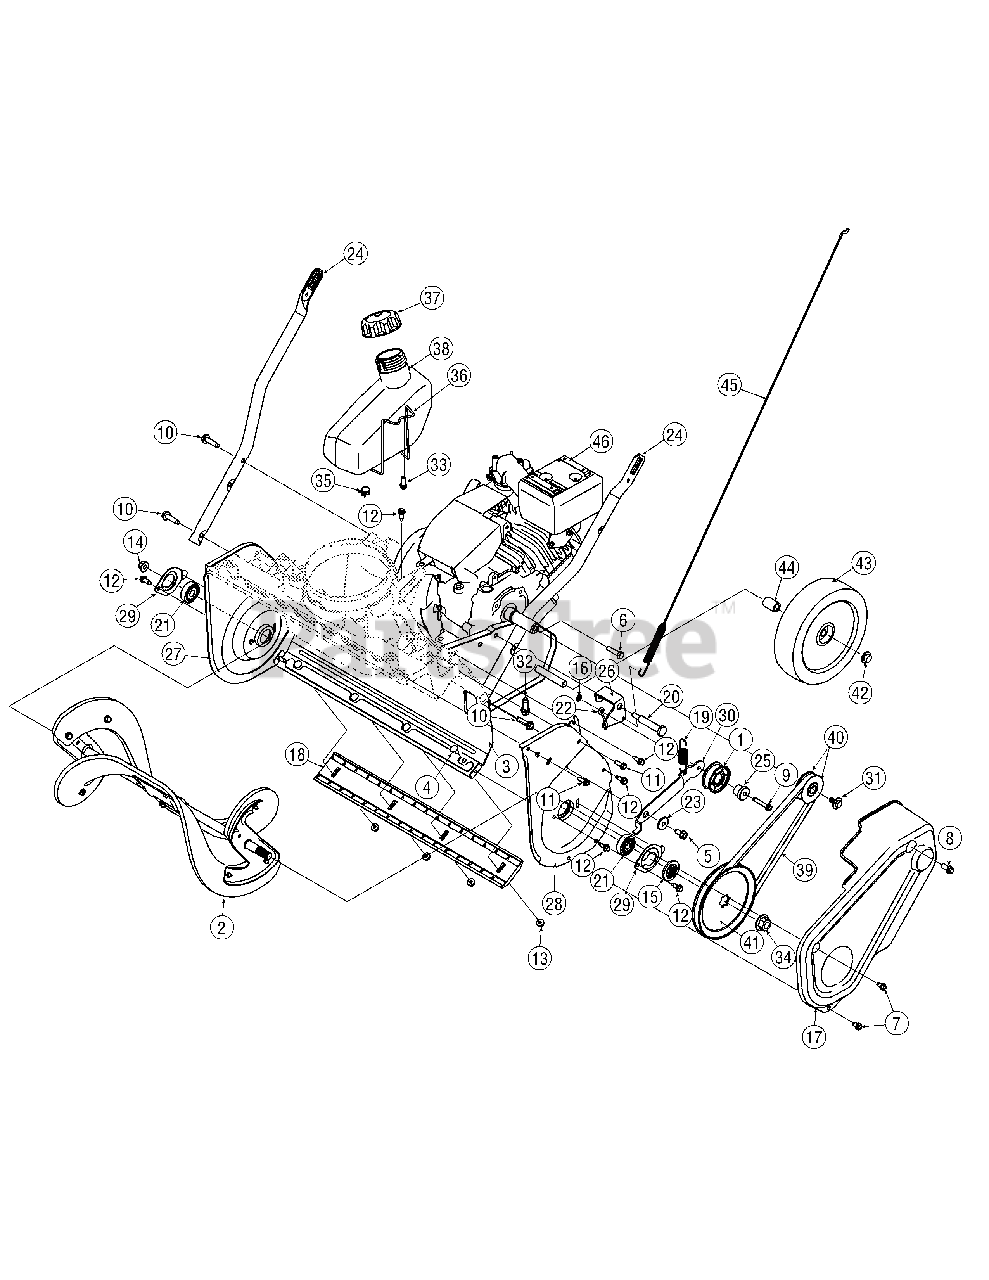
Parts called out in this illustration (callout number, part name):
1	Idler Pulley Assembly
2	Auger Assembly Complete
2	Hex Washer Screw 1/4-20 x.750
3	Frame Assembly
4	Carriage Screw, 1/4-20 x .62
5	Hex Washer Screw, 5/16-18 x .750
6	Hex Screw, 5/16-24 x 1.25
7	Hex Washer Screw, 1/4-20 x .500
8	Hex Lock Screw, 5/16-24 x .750
9	Hex Washer Screw, 1/4-20 x 1.500
10	Hex Washer Screw, 5/16-18 x 1.250
11	Hex Washer Screw, 1/4-15 x .750
12	Hex Washer Screw, 1/4-20 x .625
13	Flange Lock Nut, 1/4-20
14	Flange Lock Nut, 3/8-16
15	Pulley Hub
16	Push Nut, .25 x .50
17	Belt Cover
18	Shave Plate
19	Extension Spring, .70 x 3.035
20	Shoulder Bolt, 5/16-24 x .496 x 2.18
21	Ball Bearing, .5000 x 1.375 x .4375
22	Drive Cable Wire Support
23	Shoulder Spacer
24	Lower Handle
25	Shoulder Spacer
27	RH Side Plate
28	LH Side Plate
29	Bearing Cup
30	Idler Bracket
31	Hex Screw, 5/16-24 x .750
32	Hex Washer Screw, 3/8-16 x 1.000
33	Hex Washer Screw, 1/4-15 x .750
34	Flange Nut, 7/16-20
35	Hose Clamp, .490
36	Gas Tank Wire Support
37	Fuel Cap
38	Fuel Tank
39	Belt, .500 x 35.06
40	Pulley Half, .625 x 2.25
41	Pulley
42	Push Cap, 1/2
43	Wheel, 8"
44	Spacer, .525 x .775 x .835
45	Clutch Cable
46	Replacement Engine
